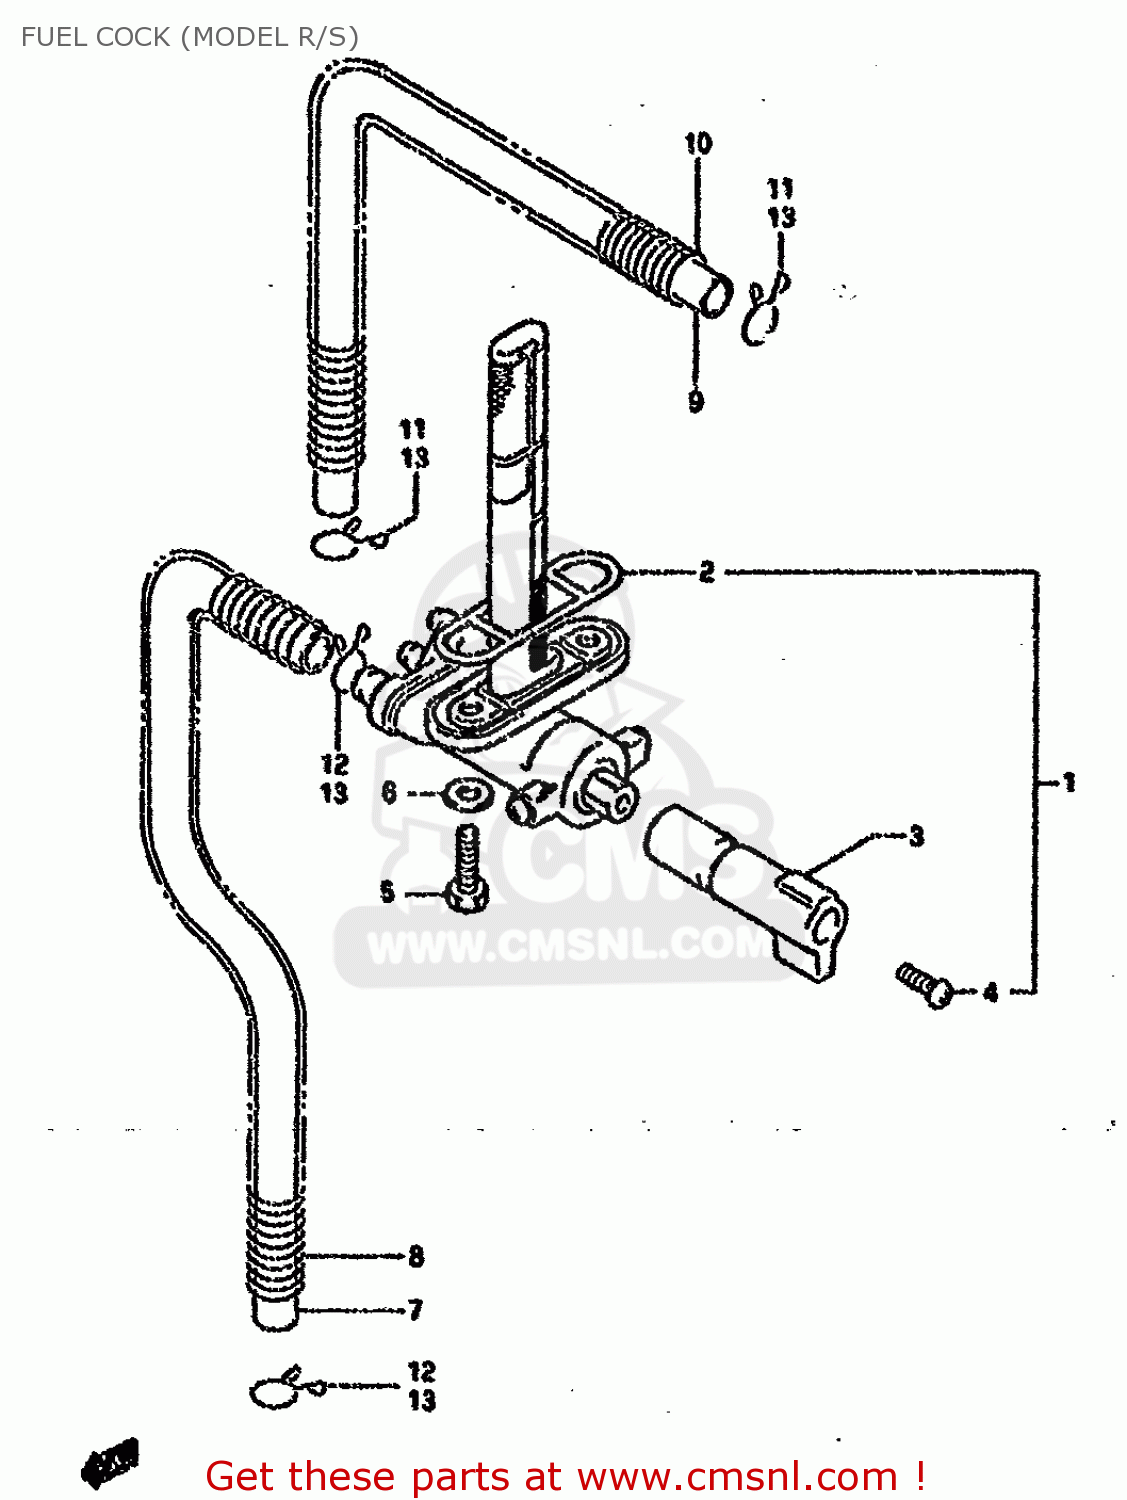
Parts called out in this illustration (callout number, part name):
1	COCK ASSEMBLY,FUEL
2	O RING,FUEL TANK JOINT
3	LEVER COCK FUEL
4	SCREW
5	BOLT(6X20)
6	GASKET(6.4X11.5X0.8) (NAS)
7	HOSE(7X10.2X600)
8	SPRING
9	HOSE
10	SPRING
11	CLIP
12	CLIP
13	CLIP
